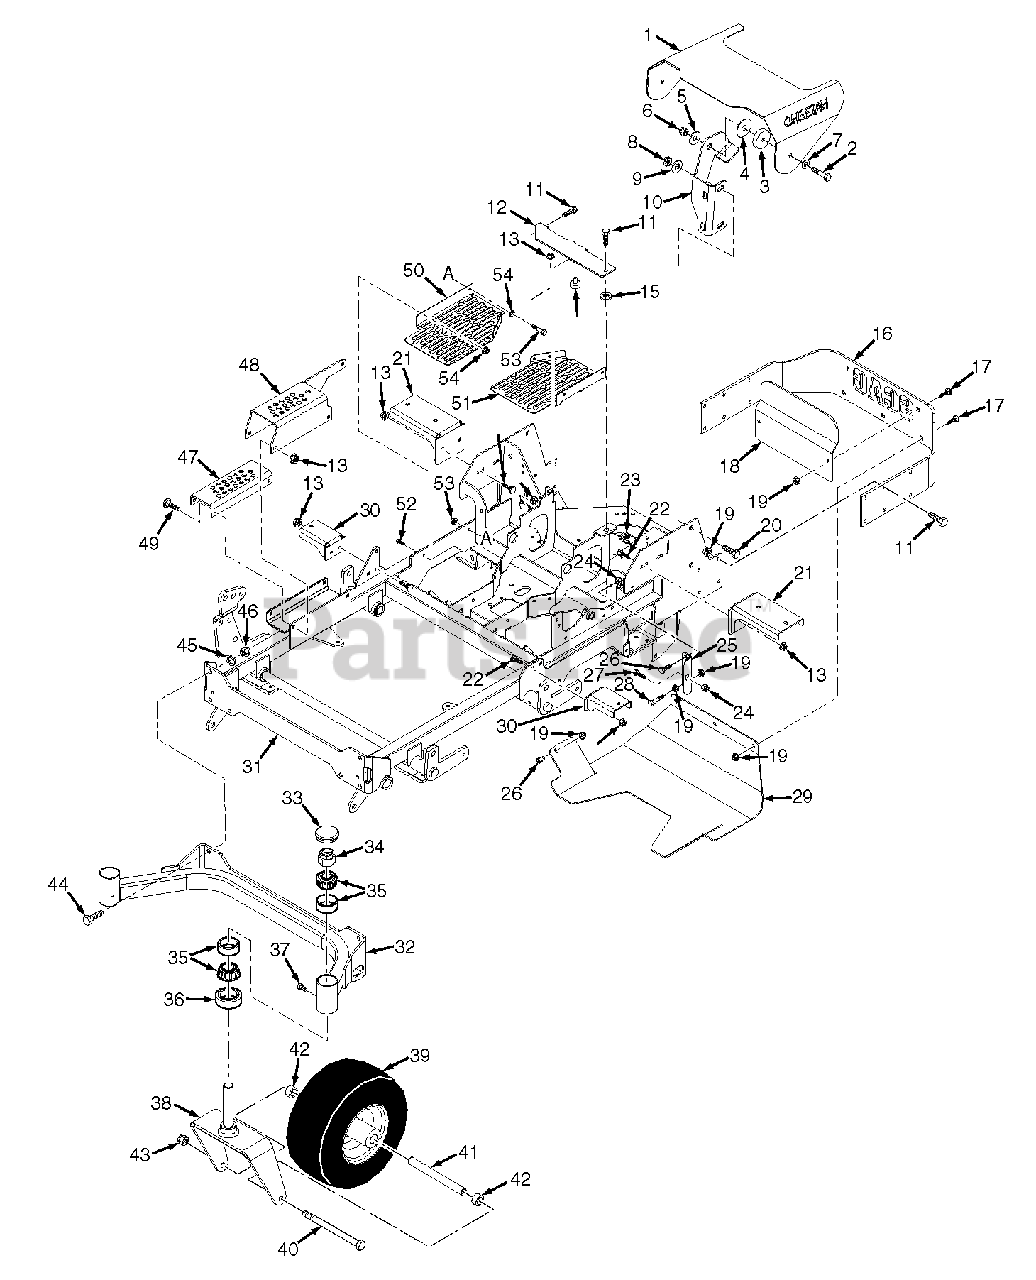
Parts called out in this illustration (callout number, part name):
1	Hood Assembly
2	Bolt, Hex Head 3/8-16 x 1-3/4"
3	Spacer, Hood
4	Disk, Anti-Friction
5	Flatwasher, 3/8-.406 x 1.50 x 7 Ga.
6	Nut, Elastic Stop 3/8-16
7	Flatwasher, 3/8-.391 x .938 x .105
8	Nut, Center Lock 1/2-13
9	Flatwasher, 1/2-.562 x 1.375 x .109
10	ROPS Mount, LH
10	ROPS Mount, RH
11	Bolt, Hex Head 3/8-16 x 1"
12	Cover, Battery Box
13	Nut, Serrated Flange 5/16-18
14	Bumper, Rubber
15	Nut, Push-On 3/8 Thread
16	Bumper, Rear
17	Bolt, Carriage 3/8-16 x 1"
18	Guard, Engine
19	Nut, Serrated Flange 3/8-16
20	Bolt, Hex Head 1/2-13 x 1-1/4"
21	Mounting Bracket, Fuel Tank Rear
22	Bolt, Carriage 5/16-18 x 3/4"
23	U-Nut, 3/8-16
24	Nut, Elastic Stop 3/8-16
25	Anchor Bracket, Pum Spring
26	Bolt, Hex Head 3/8-16 x 1"
27	Bolt, Hex Head 3/8-16 x 1-1/4"
28	Bolt, Hex Head 3/8-16 x 1-1/2"
29	Plate, Skid
30	Mounting Bracket, Fuel Tank Front
31	Mainframe Assembly, w/Decals
32	Caster Weldment
33	Cap, Grease
34	Nut, Elastic Stop 1"-14
35	Bearing w/Race
36	Seal, 2" O.D. x 1.625 Bore
37	Plug, 1/4-28
38	Yoke Weldment
39	Caster Wheel Assembly
39	Bearing
39	Grease Fitting
40	Bolt, Hex Head 1/2-13 x 9-1/2"
41	Sleeve, Caster Wheel
42	Spacer, Caster Wheel
43	Nut, Elastic Stop 1/2-13
44	Bolt, Hex Head 7/16-14 x 1-1/4"
45	Lockwasher, 7/16" Spring
46	Nut, Elastic Stop 7/16-14
47	Adjustment Bracket, Lower Cut Height
48	Adjustment Bracket, Cutting Height
49	Bolt, Carriage 5/16-18 x 1"
49	Bolt, Hex Head 5/16-18 x 1"
49	Lockwasher, 5/16" Spring
50	Fan Cover, RH
51	Fan Cover, LH
52	Bolt, Hex Head 1/4-20 x 3/4"
53	Bolt, Hex Head 1/4-20 x 1-1/4"
54	Nut, Serrated Flange 1/4-20
